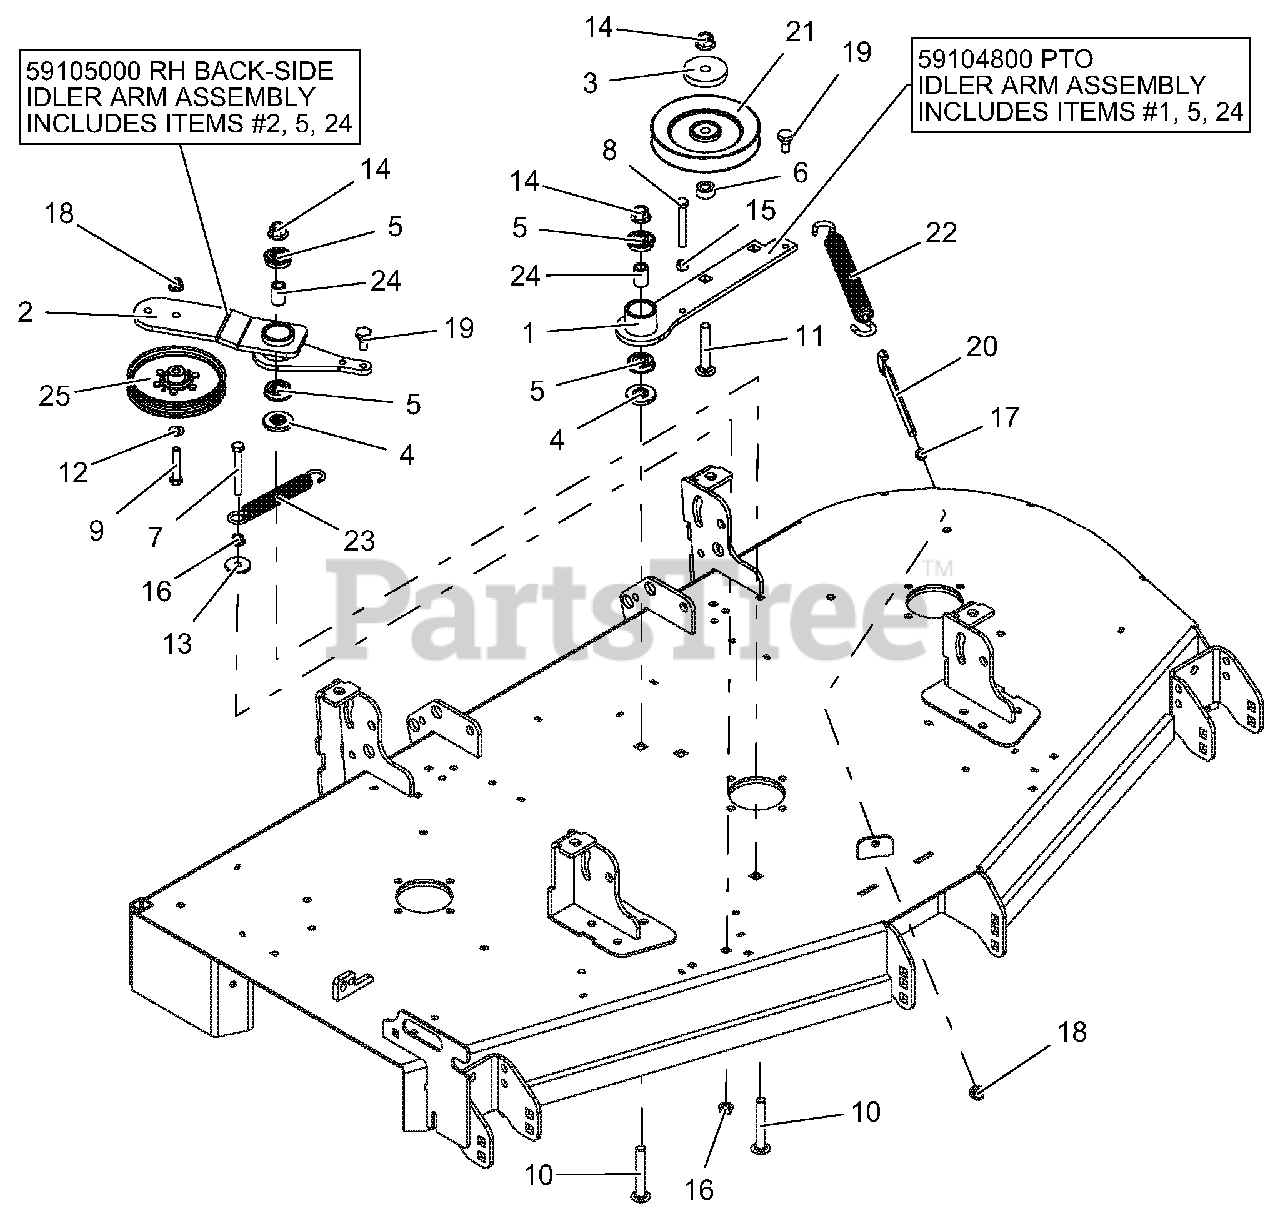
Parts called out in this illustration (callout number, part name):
1	WLDMT, DECK PTO IDLER ARM-BLACK
2	WLDMT, DECK RH IDLER ARM
3	CAP, IDLER BEARING SEALING
4	SPACER, IDLER ARM
5	BRG, BALL .501 X 1.38 X .438 SEALED
6	BSHG, SPCR .502 X .997.50 PM
7	BLT-HEX .38-16X3.00 GR5 YWZC
8	BLT-HEX .38-16X2.75 GR5 YWZC
9	BLT-HEX .38-16X2.00 GR5 YWZC
10	BLT-RDHDSQSHNK .50-13X3.25 YWZC
11	BLT-RDHDSQNK .50-13X3.00 G5 Y
12	WSHR-FL-STL.406X.812X.065 YWZ
13	WSHR-FL-STL .406X1.375X.135 YZ
14	NUT-LK-NYL-FLG .50-13 YWZC
15	NUT-HEX .38-16 YWZC
16	@NUT-SPNLK-FLG .375-16 YWZC
17	NUT, JAM .375-16 YWZC
18	NUT-LK-NYL-FLG .38-16 YWZC
19	BLT, SHLDR EP .38-16X.30 HEX YZ
20	BOLT, .38-16X6.00 .62 DIA EYE
21	SHEAVE, .50" ID X 6.00" OD V-IDLER
22	SPRG, EXTENSION
23	SPRG, EXTENSION
24	SPACER, .510 X .750 X 1.148
25	PULLEY, FLAT IDLER .500 X .375 W/BRG
